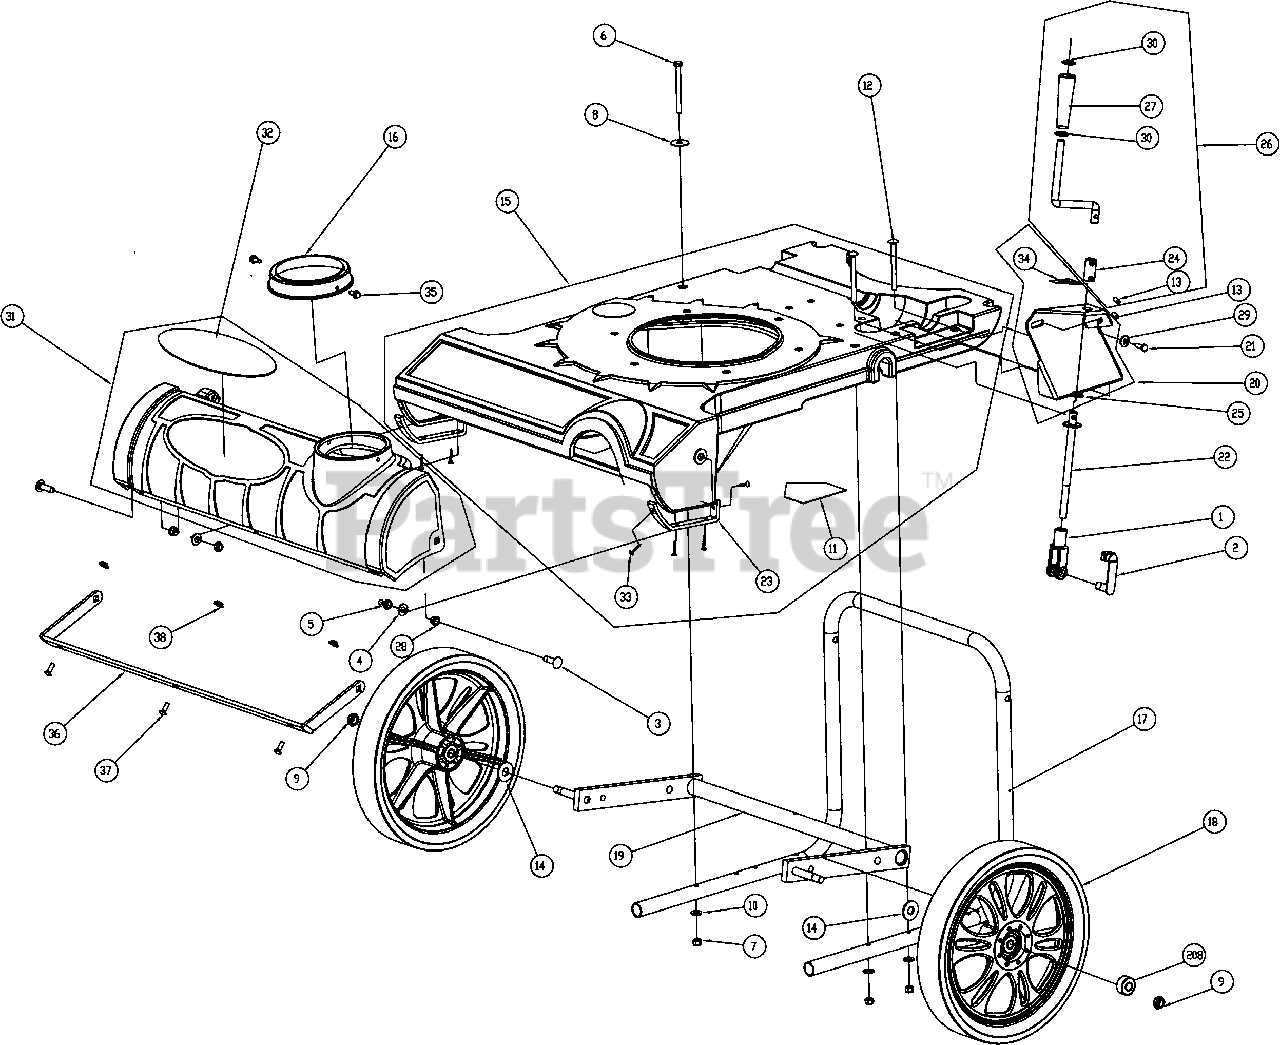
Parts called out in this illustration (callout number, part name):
1	YOKE 1/2 - 20
2	PIN YOKE 1/2"
3	SCREWCAP BUTTON HEAD 3/8"-16 X 1 1/4" PL
4	WASHER 3/8" SAE ZP
5	NUT LOCK 3/8-16 LT WT THIN ZP
6	SCREWCAP 5/16 -18 x 3 1/2
7	NYLON INSERT LOCKNUT 5/16-18 UNC
8	WASHER FLAT FENDER 5/16
9	NYLON INSERT LOCKNUT 1/2-13 UNC THIN
10	WASHER 1/4" FC ZP
11	LABEL WARNING OPEI
12	BOLTCARRIAGE 5\16-18X3 1\2
13	ROLL PIN 1/4 X 1 LONG
14	WASHER 1/2" SAE ZP
15	NOZZLE MV VAC ASSEMBLY
16	CAP 5 IN HOSE VAC
17	HANDLE LOWER MV VAC
18	WHEEL 14" ASSEMBLY WITH BEARING AND TIRE
19	AXLE FRONT WA MV VAC
20	HGT ADJ WA W/LABEL MV VAC
21	SCREWCAP 1/4 - 20 x 0.75 HWH
22	LINK HGT ADJ MV VAC
23	BRACKET NOZZLE WEAR GUARD MV VAC
24	ROD CONNECT HGT ADJ
25	BUSHING 0.5" ID 0.625 OD X X 0.250
26	ROD HANDLE CRANK ASSEMBLY
27	HANDLE CRANK 0.5 ID X 3.72 LONG
28	BUSHING 3/8" ID 1/2" OD X 3/8" LONG
29	WASHER LOCK 1/4" TWISTED TOOTH
30	NUT PAL 0.5" ID X 0.75 OD
31	NOZZLE COVER MV VAC
32	LABEL MV BADGING
33	SCREW PLASTIC
34	LABEL HGT ADJ MV VAC
35	SCREW PLASTITE 1/4"-10 X 3/4 HWH ZP
36	BRACKET NOZZLE COVER REINFORMENT MV
37	BOLT CARRIAGE 1/4-20X0.75
38	NUT FLANGE 1/4-20
208	MV WHEEL BEARING
